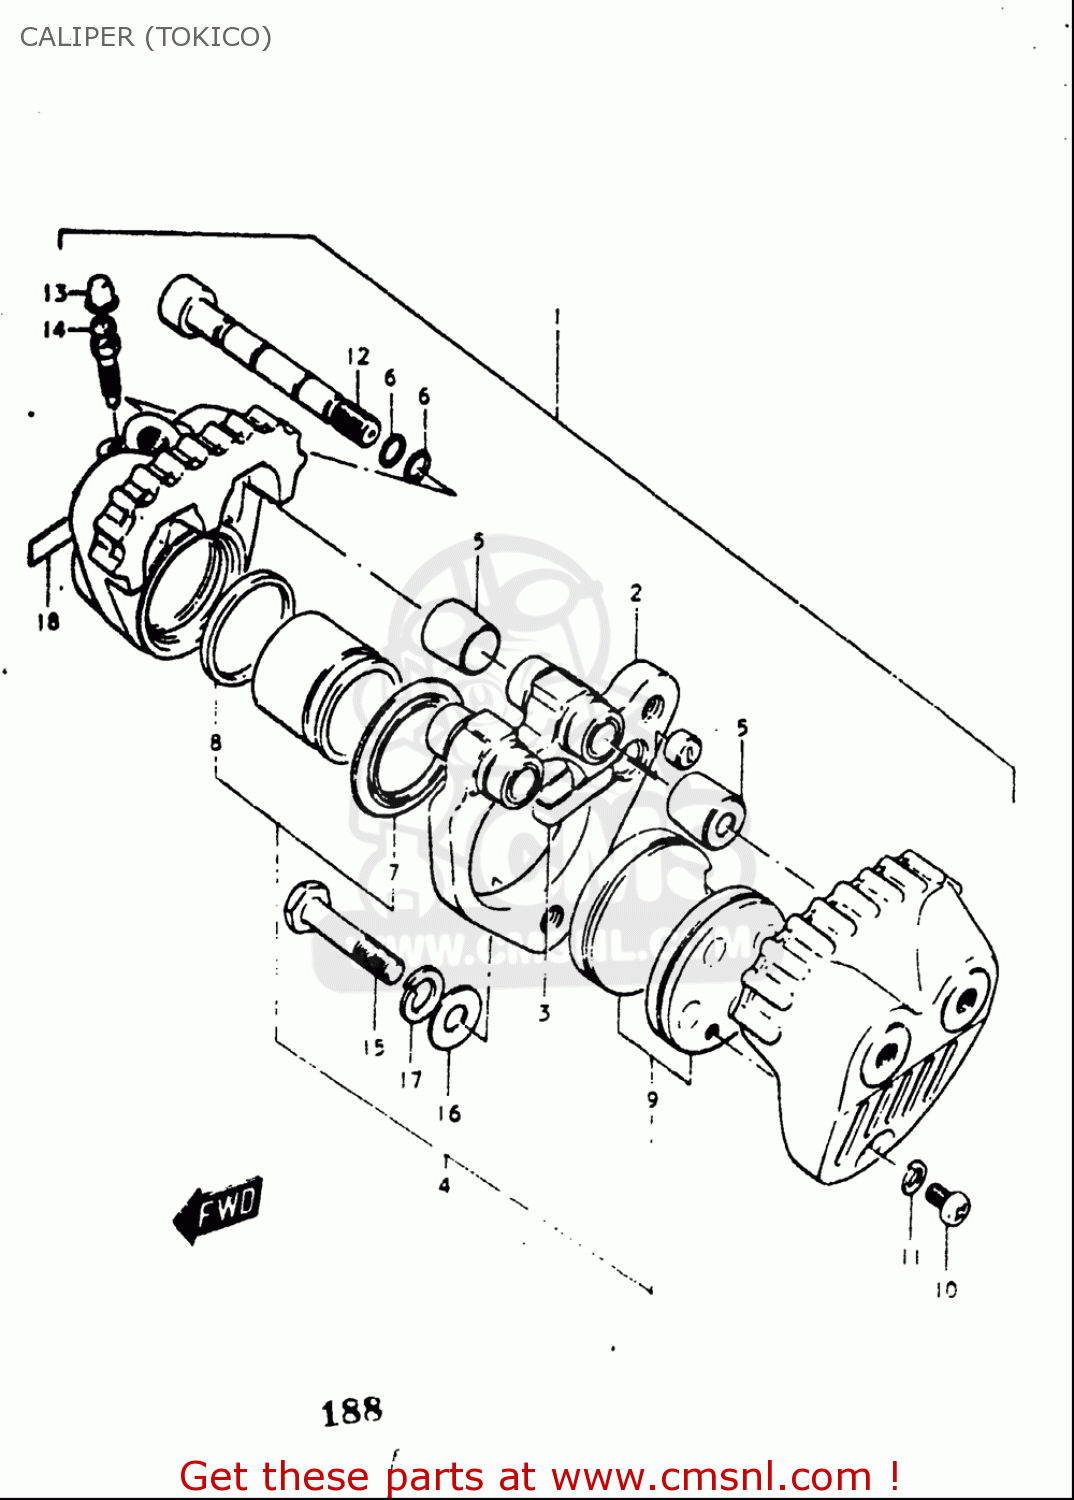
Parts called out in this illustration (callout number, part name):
4	PISTON SET
5	COVER,AXLE DUST
6	O RING,CALIPER AXLE
7	BOOT,PISTON
8	SEAL,PISTON
9	PAD SET (NAS)
10	SCREW
11	WASHER,LOCK
12	AXLE,CALIPER
13	CAP,BLEEDER PLUG
14	BLEEDER
15	BOLT(10X38)
16	WASHER
17	WASHER,LOCK
